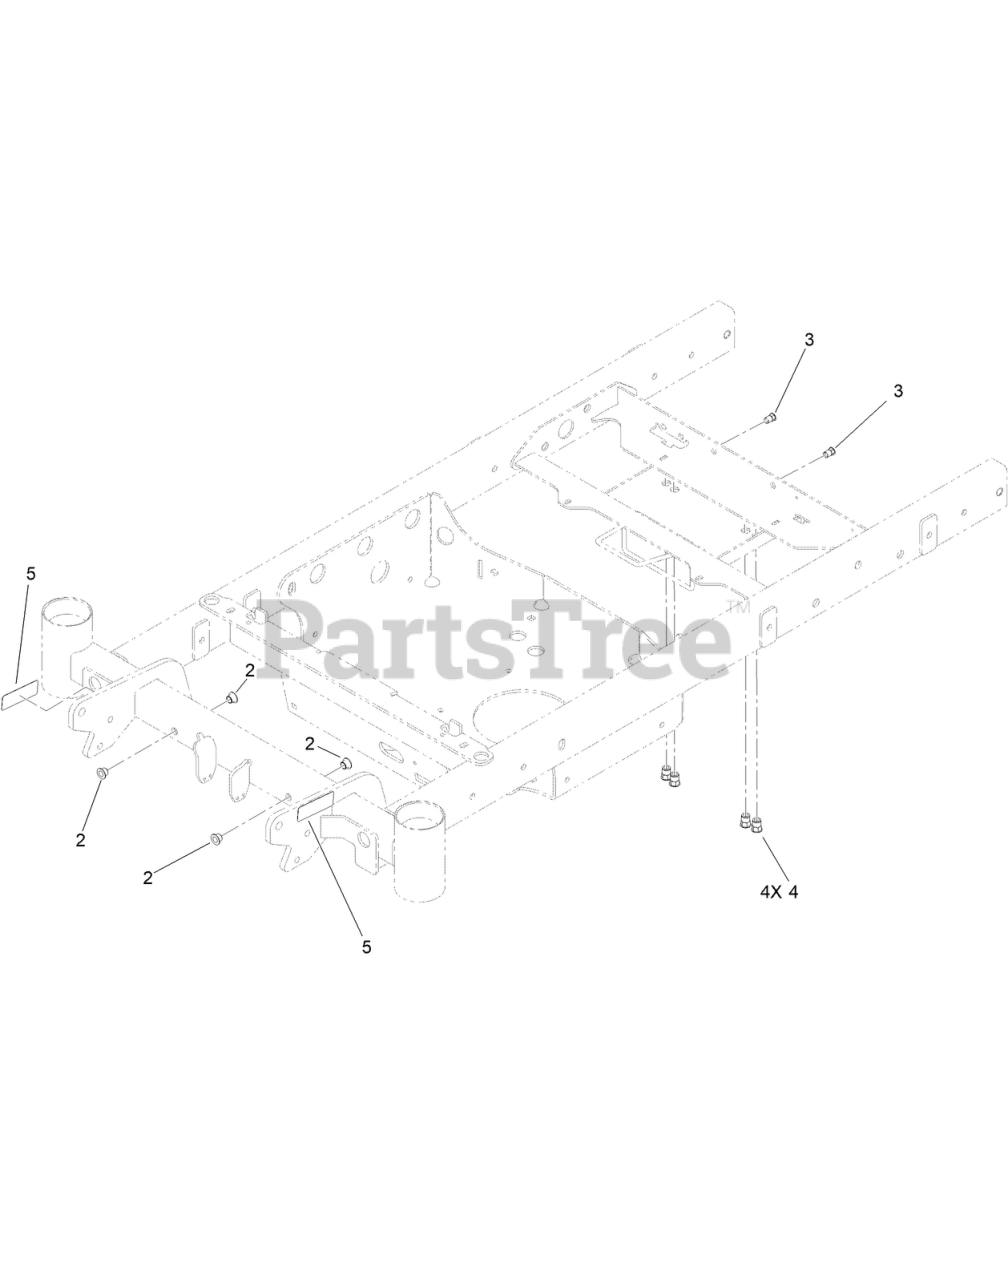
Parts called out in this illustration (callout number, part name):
2	BUSHING-FLANGE
3	Nut-Clinch, Hex
4	NUT-CLINCH,HEX
5	DECAL-WARNING, PINCH POIN
